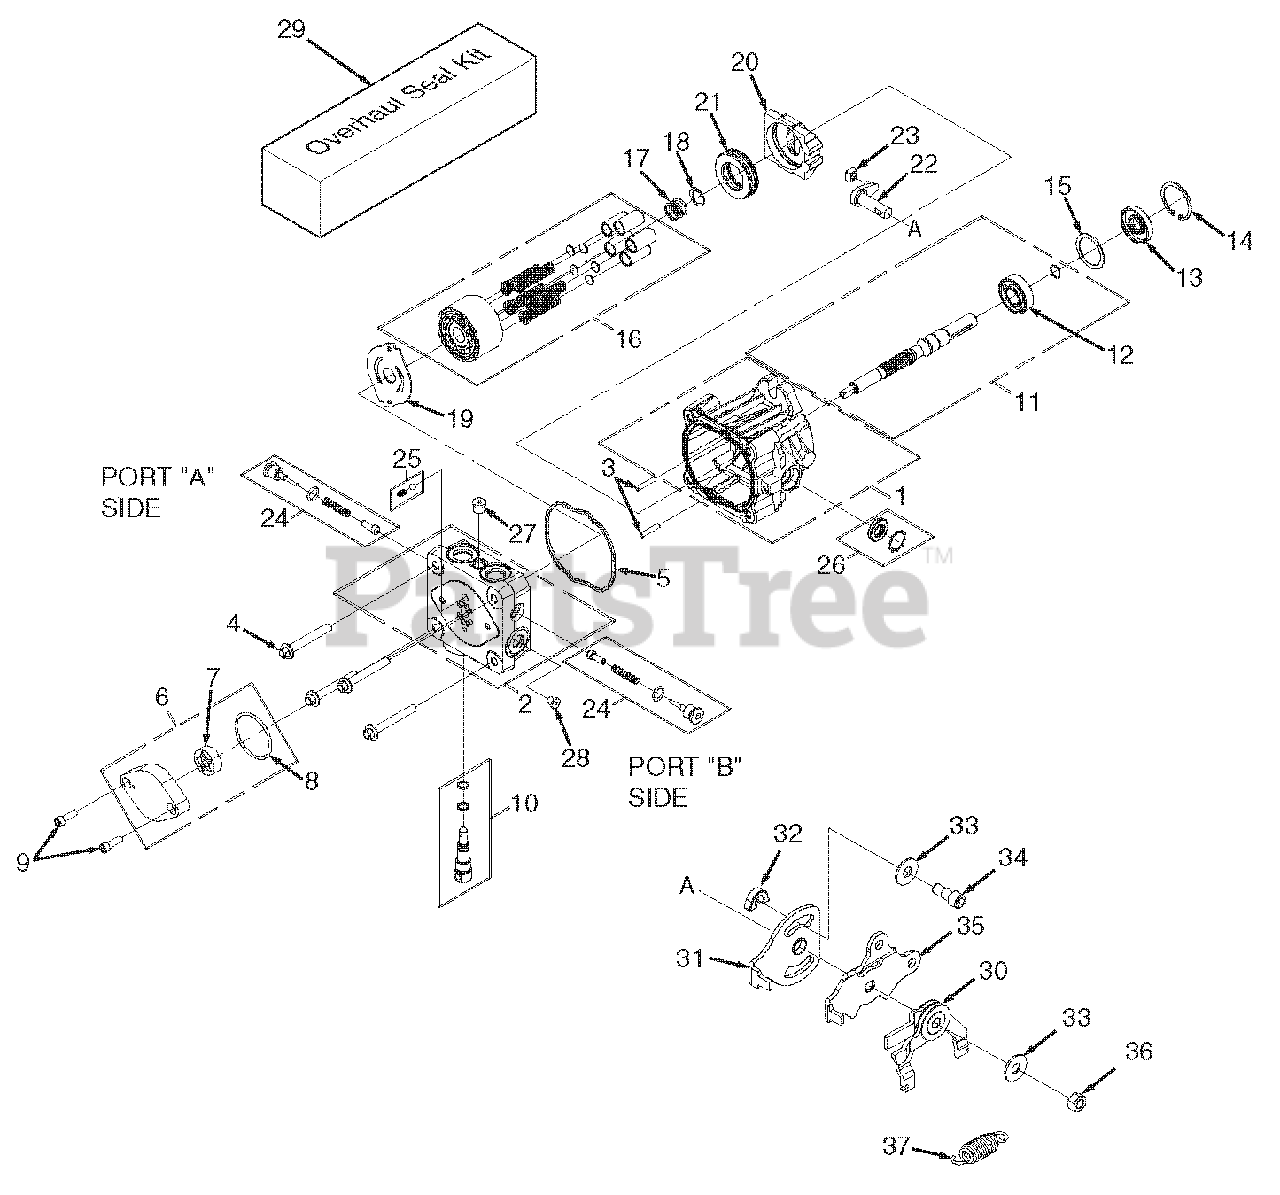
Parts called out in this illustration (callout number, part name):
1	Kit, Housing
2	Kit, End Cap
3	Pin, .219 x 1.000
4	Bolt, M8 X 1.25 mm
5	Gasket, Housing
6	Kit, Charge Pump
7	Gerotor Assembly
9	Screw, Socket Head M6 X 1.0 - 20mm
10	Kit, By-Pass
11	Kit, Shaft
12	Bearing
13	Seal, 17 x 40 x 7 Lip
14	Ring, Retaining .156 Internal
15	Washer, 1.23 x 1.57 x .04
16	Kit, Block 10cc
17	Spring, Block
18	Washer, .59 x .79 x .04
19	Plate, Valve 10cc
20	Swashplate
21	Bearing, Thrust
22	Arm, Trunion
23	Slot Guide
24	Kit, Check Valve (.031 Orifice)
25	Kit, Charge Relief
26	Kit, Seal
27	Plug, 7/16-20
28	Plug, 9/16-18
29	Seal Kit
30	RTN Assembly
31	Arm, Return
32	Spacer
33	Washer
34	Screw, 5/16-24 x 3/4" w/Patch
35	Control Arm
36	Nut, Center Lock 5/16-24 UNF
37	Spring, External
